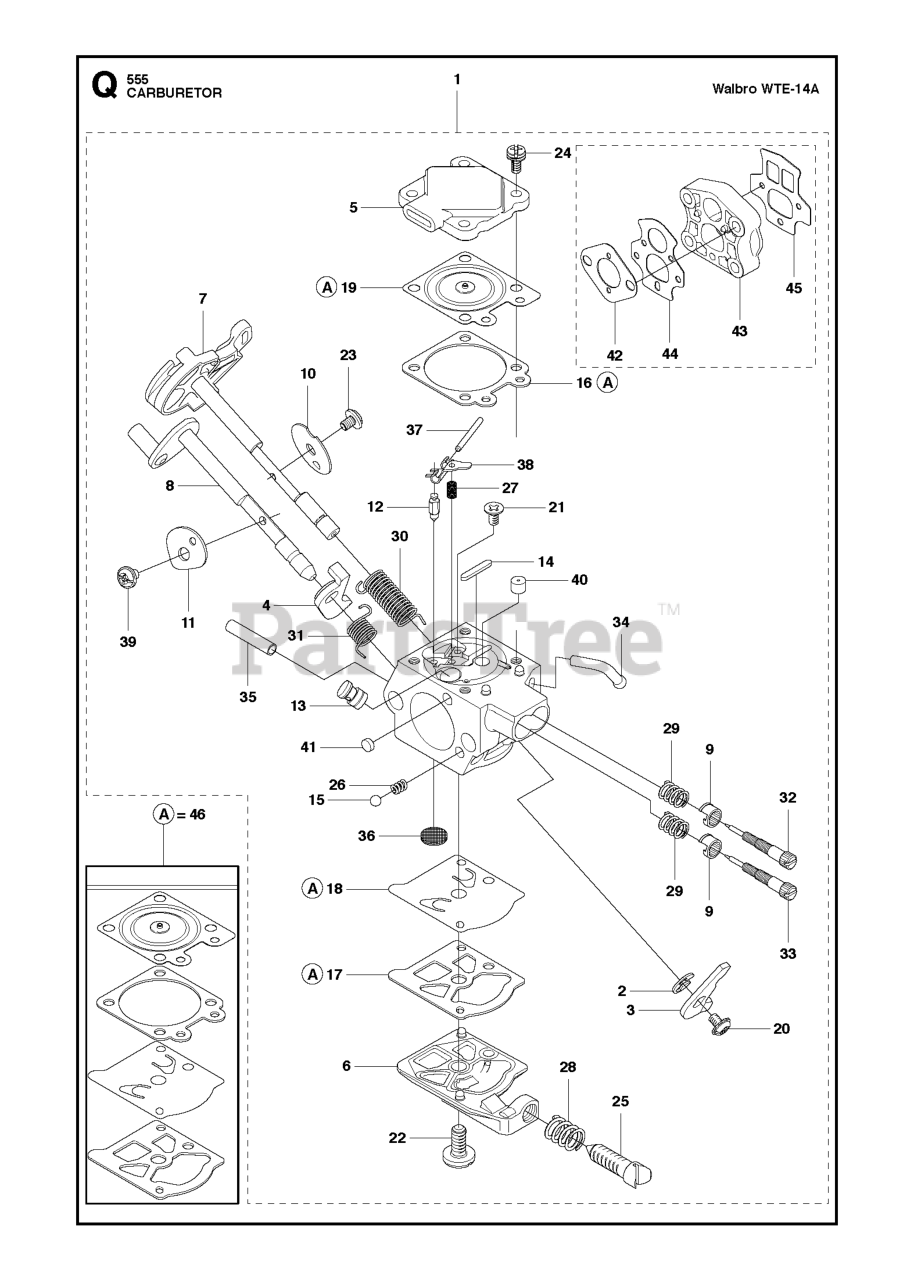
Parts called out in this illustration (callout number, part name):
1	CARBURETOR KIT
1	CARBURETOR
2	E CLIP
3	LEVER
4	LEVER
5	DIAPHRAGM COVER
6	COVER
7	SHAFT
8	SHAFT
9	LIMITER CAP
10	VALVE
11	VALVE
12	INLET NEEDLE
13	NOZZLE ASSY
14	PLUG
15	BALL
16	GASKET
17	GASKET
18	DIAPHRAGM
19	DIAPHRAGM
20	SCREW
21	SCREW
22	SCREW
23	SCREW
24	SCREW
25	SCREW
26	SPRING
27	SPRING
28	SPRING
29	SPRING
30	SPRING
31	SPRING
32	NEEDLE
33	NEEDLE
34	FITTING
35	FITTING
36	FUEL INLET SCREEN
37	FULCRUM PIN
38	LEVER
39	SCREW
40	JET
41	PLUG WELCH
42	Husqvarna TBD
43	Husqvarna TBD
44	Husqvarna TBD
45	Husqvarna TBD
